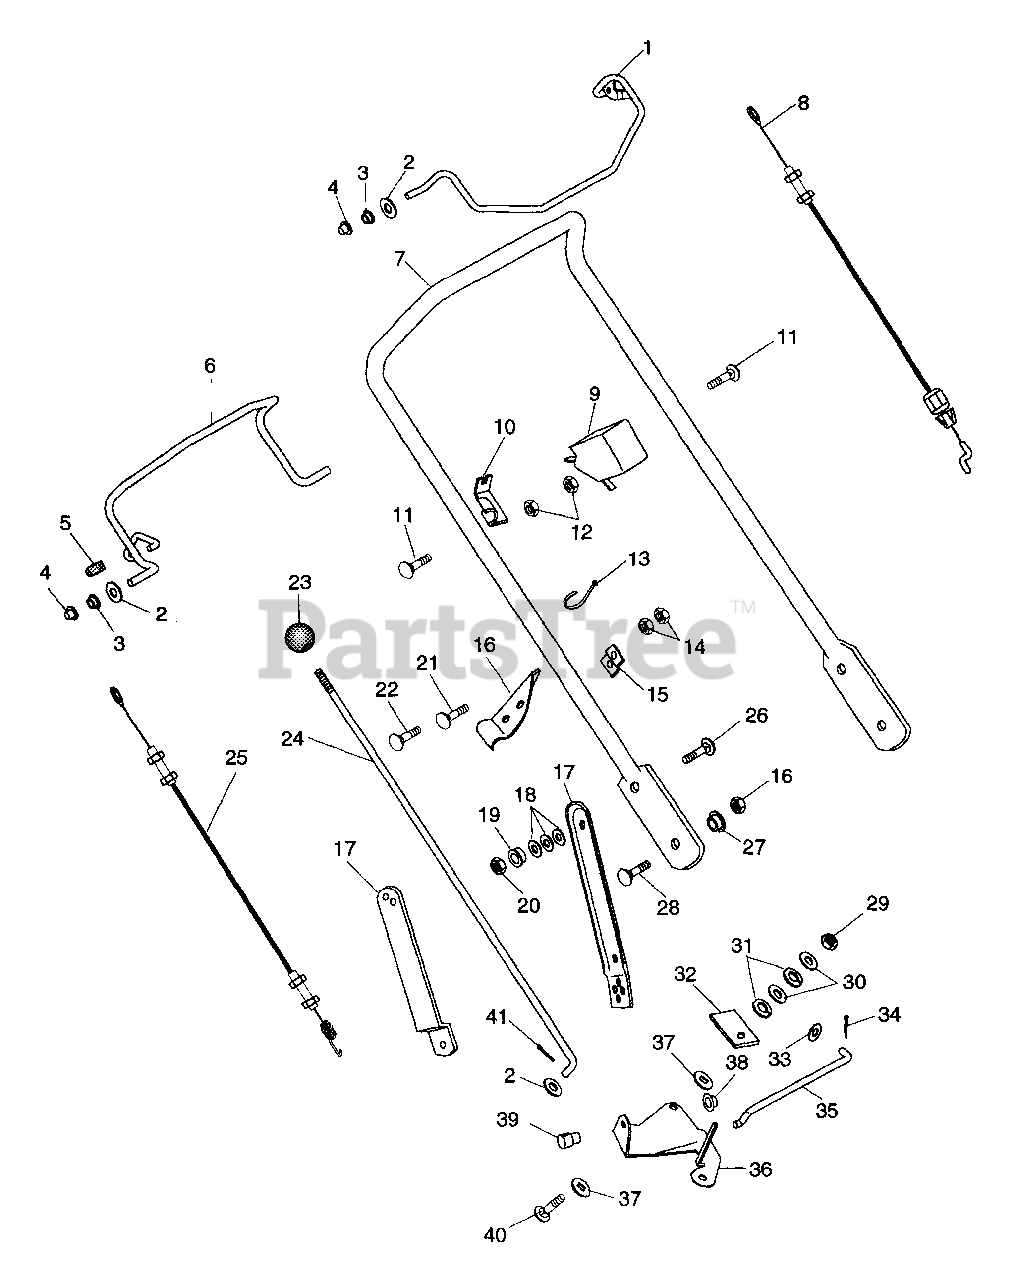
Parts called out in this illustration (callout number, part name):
1	ENGINE BAIL
2	WSHR-FL-STL.344X.688X.065PL
3	BSHG-FLG .325X.444X.440X.560
4	NUT-PUSH .312 DIA. PAL
5	CAP, VINYL, .25 ID
6	TRACTION BAIL-COATED
7	HANDLEBAR
8	ENGINE CONTROL CABLE
9	SWITCH-CABLE ANCHOR
10	CABLE ANCHOR
10	CABLE ANCHOR-LH
11	BLT-RDHDSQNK .25-20X1.25 XLGPL
12	NUT-KEPS .250-20
13	CABLE TIE LG 5-1/2
14	NUT-LK-CTR .250-20 PL
15	BRACE-SPEED CONTROL
16	BRACKET-SPEED CONTROL
17	LINK,HANDLE BAR ADJUST LH
17	LINK,HANDLE BAR ADJ RH
18	WASHER,BELLEVILLE SPRING
19	BSHG-FLG .325X.500X.513X.875
20	NUT-LK-TOP .312-18 GR C PL
21	BLT-RDHDSQNK .25-20X1.38SHT PL
22	@BLT-RHDSSQNK .25-20X.38 G2YZ
23	KNOB, BALL 5/16-18 X 1.5
24	ROD-SPEED CONTROL
25	TRACTION CABLE
26	BLT-RDHDSQNK .31-18X1.12 GR5PL
27	BSHG, FLG .325X.499X.26X.88
28	BLT-RDHDSQNK.31-18X.88 GR5YWZC
29	NUT-LK-CTR .375-16 GR A PL
30	WSHR-FL-STL.406X.812X.065PL
31	WSHR-LK .375X.115 HVY PL
32	PRESSURE FLANGE
33	WSHR-FL-STL.281X.62X.065 PL
34	PIN-COTR .06X.50
35	SHIFT LINK
36	BELL CRANK - SPEED CONTROL
37	FRICTION WASHER
38	CAP, 3/8 ROD YWZC
40	BLT-RDHDSQNK .38-16X1.50 PL
41	PIN-HAIR INT .08X.18X1.18
